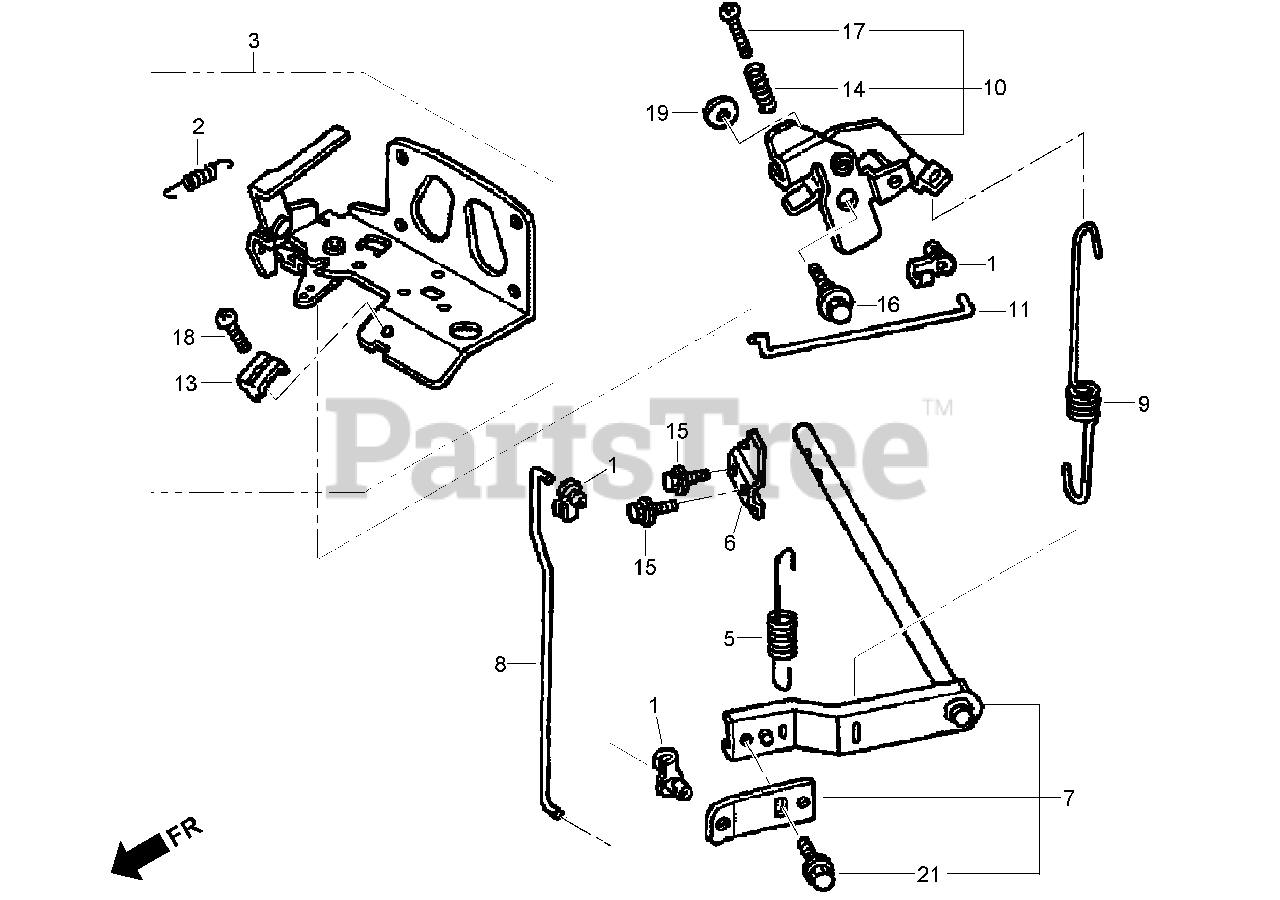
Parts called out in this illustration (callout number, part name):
1	ROD-JOINT
2	SPRING-RETURN, CHOKE
3	CONTROL ASM (1-LEVER)
5	SPRING-STARTER
6	FORK-GOVERNOR
7	ARM-GOVERNOR
8	ROD-GOVERNOR
9	SPRING-GOVERNOR
10	LINK-GOVERNOR
11	ROD-LINK, GOVERNOR
13	Holder-Cable
14	SPRING-ADJUSTING, CONTROL
15	BOLT-FLANGE (5X10)
16	BOLT-FLANGE (6MM) (C T200)
17	SCREW-RECESSED (5X25)
18	SCREW-RECESSED (5X18)
19	WASHER-PLAIN (6MM)
21	Bolt-Flange (6X10)
